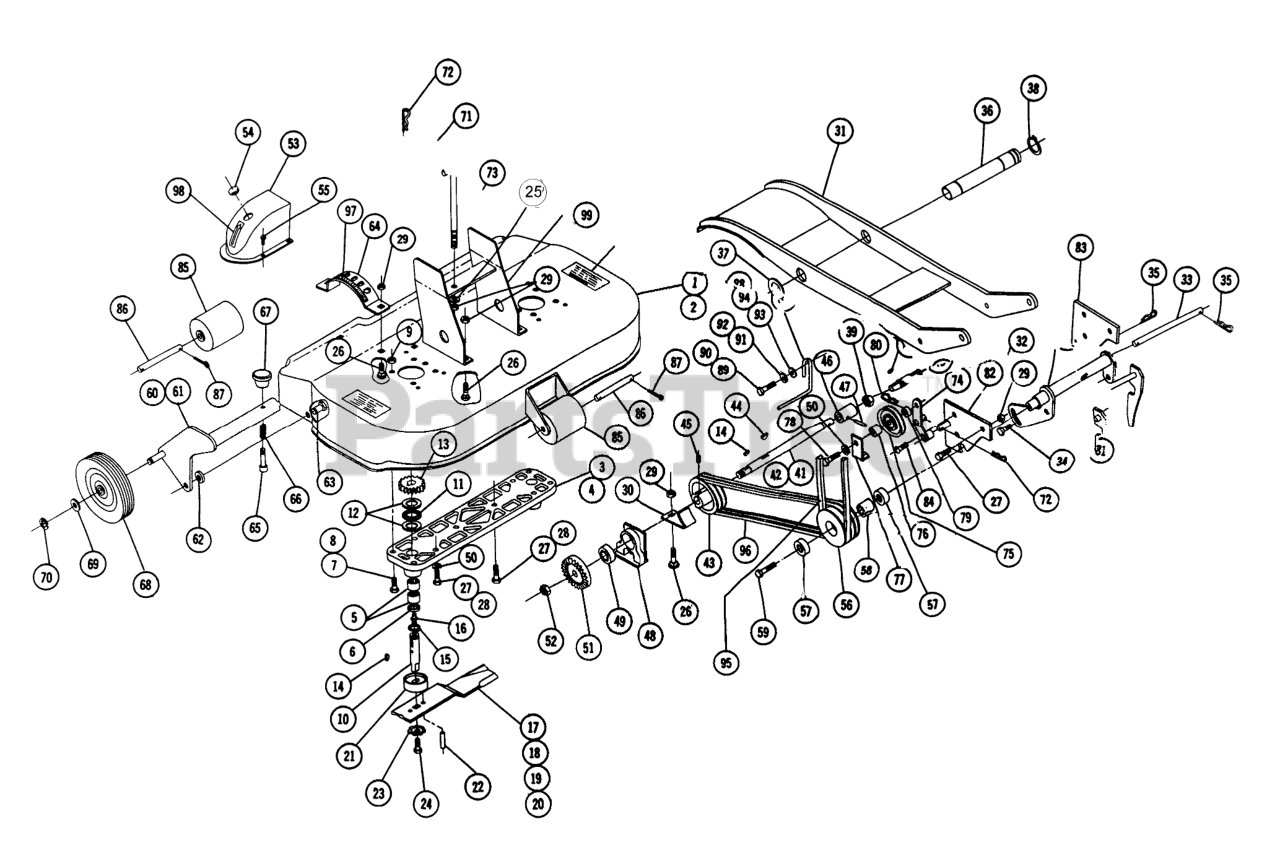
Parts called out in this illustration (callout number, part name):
1	Ass-y. Deck
2	Ass-y Deck
3	Housing
4	Housing
5	NEEDLE BEARING
6	Seal
7	Bolt, 5/16-18 X 7/8
8	Bolt 5/16-18 x 11/4
9	Nut 5/16-18
10	Spindle
11	Bearing Thrust
12	WASHER-THRUST
13	SPUR GEAR
14	WOODRUFF KEY
15	RING-SNAP, EXTERNAL
16	Zerk
17	Blade R.H. 15"
18	Blade L.H. 16"
19	Blade R.H. 18"
20	Blade L.H. 18"
21	SPINDLE CUP
22	SPIROL ROLL PIN
23	WASHER
24	Bolt 3/8-16 x 7/8
25	Ass-y Bracket-Hanger
26	Bolt-3/8-16 x 3/4
27	Bolt 3/8-16 x 1
28	Bolt 3/8-16 x 1
29	3/8-16 E.S.
30	Guard
31	Ass-y-Drag Link
32	ASSY HITCH SHAFT R
33	Pin-Hitch
34	Bolt Whizlock 3/8-16 x 5/8
35	Hairpin
36	PIVOT TUBE
37	Washer
38	SNAP RING
39	Nut Hex Jam 3/4-20
40	Shaft-Short
41	Cross Shaft-Long
42	Cross Shaft (Long)
43	PULLEY
44	Key
45	Set Screw
46	Coupling
47	Spiral Pin
48	Housing
49	Ball
50	Lockwasher
51	Gear
52	Nut Hex 5/8-18 Thin
53	COVER GEAR
54	PLUG BUTTON
55	SCREW
56	PULLEY
57	BALL BEARING
58	SPACER-BEARING
59	SPECIAL BOLT
60	Ass-y-Support-Wheel
61	Ass-y Support-Wheel
62	WASHER
63	Bolt-Special
64	QUADRANT R
65	PLUNGER
66	Spring
67	KNOB
68	WHEEL ASSY
69	SHIM-WASHER
70	E Ring
71	LIFT ROD R
72	Hairpin
73	Washer
74	Ass-y Idler Arm
75	Pulley
76	SPACER
77	BRACKET GUARD
78	Bolt, 3/8-16 x 1/2
79	BUSHING
80	Hairpin
81	Ass-y Latch & Shaft
82	Ass-y Plate Pin R.H.
83	PLATE-MTG BRKT LH R (NS)
84	Bolt 3/8-16 x 1 RD.HD.
85	Roller
86	Shaft
87	Cotter Pin
88	RETAINER BELT
89	Bolt Round Head 5/16-24 x 3/4
90	Bolt 3/8-16 x 3/4
91	Lockwasher
92	Lockwasher
93	Washer
94	Washer
95	V BELT
96	V-BELTS - MATCHED PR
97	Decal-Height Control
98	Decal
99	Decal
